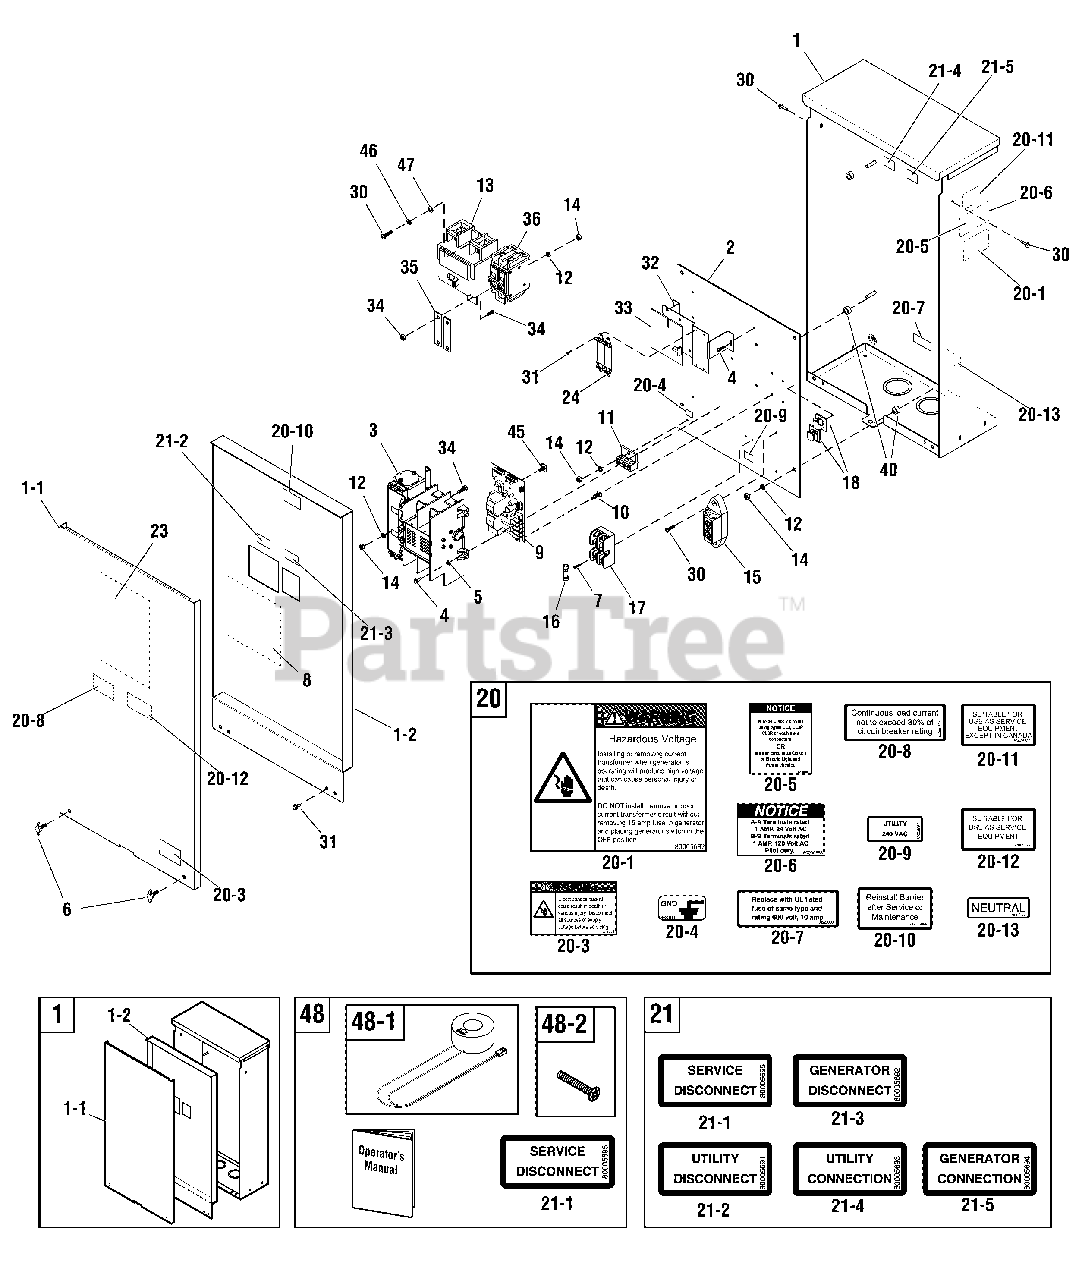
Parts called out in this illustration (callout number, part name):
1	ENCLOSURE
2	BACK PANEL
3	SWITCH, Transfer
4	* SCREW, Hex Head, Trilobular, #10-32 x 1/2
5	* WASHER-EXT. #10
7	* SCREW, Hex Head, Trilobular, #6-32 x 3/8
8	INSULATION, Dead Front
9	BOARD, Circuit
10	SPACER, PCB Board, 1/2
11	LUG
12	* WASHER, Lock, 1/4
13	BREAKER, Circuit, 200A
14	* NUT, 1/4-20
15	TERMINAL, Neutral
20	DECAL SHEET - WARNINGS
20-1	DECAL, Warning Voltage
20-3	DECAL, Warning Shock
20-4	DECAL, Ground
20-5	DECAL, Notice
20-6	DECAL, Contacts Rated
20-7	DECAL, Fuse, 10 Amp
20-8	DECAL, Breaker, Circuit
20-9	DECAL, Sensing, Utility
20-10	DECAL, Reinstall After
20-11	DECAL, Not Suitable
20-12	DECAL, Suit. as Service Equip.
20-13	DECAL, Neutral
21	DECAL SHEET-CONNECTIONS
21-2	DECAL, Disconnect Utility
21-3	DECAL, Gen Disconnect
21-4	DECAL, Connection, Utility
21-5	DECAL, Connect Gen
30	* SCREW, Hex Head, Trilobular, #10-32 x 3/4
31	* SCREW, Hex Head, Trilobular, 8-32 x 3/8
33	INSULATOR, Circuit Breaker
34	* SCREW, Phillips Head, 1/4-20 x 3/4
35	BAR, Bus
36	BREAKER, Circuit, 100A
40	SPACER
46	* WASHER, Lock, #10
47	* WASHER, Flat, #10
48	KIT, Manual
48-1	CURRENT TRANSFORMER
